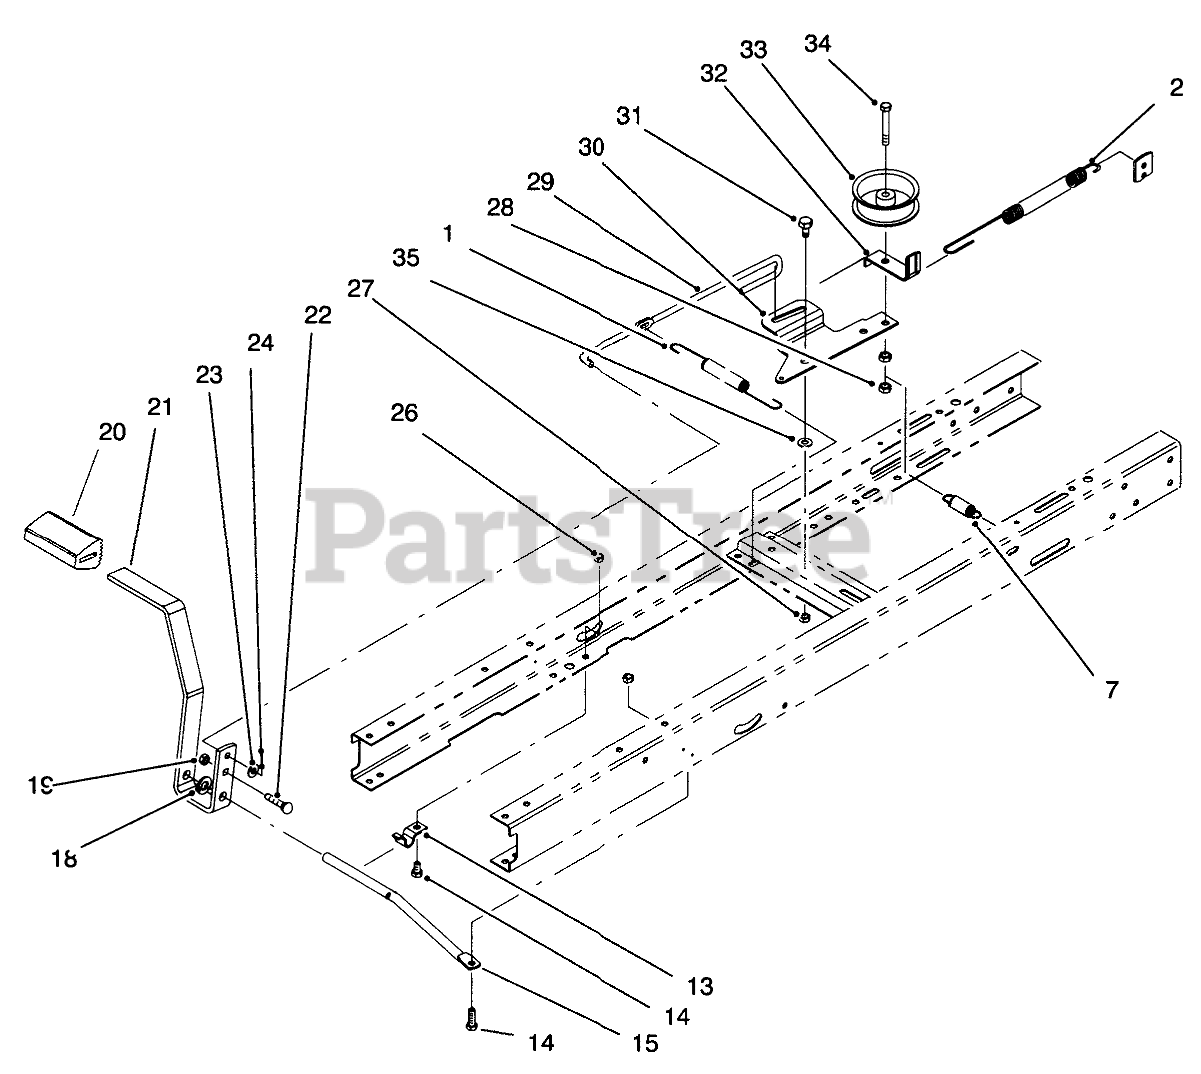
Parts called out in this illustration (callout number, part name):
1	SPRING-EXTENSION
2	BRAKE SPRING
7	SPRING-EXTENSION
13	CLAMP-PIVOT, SHIFT
14	SCREW-HH
15	ROD-PIVOT, PEDAL
18	WASHER-FLAT
19	NUT-LOCK, NI
20	PAD-PEDAL
21	Pedal-Clutch/Brake
22	SCREW-CARR
23	WASHER-PLAIN
24	PIN-COTTER
26	NUT-LOCK, NI
27	NUT-LOCK, NI
28	NUT-LOCK, NI
29	ROD-CLUTCH/BRAKE
30	ARM-IDLER
31	BOLT-SHOULDER
32	GUIDE-IDLER, BELT
33	Idler Pulley
34	SCREW-HH
35	WASHER-PIVOT
